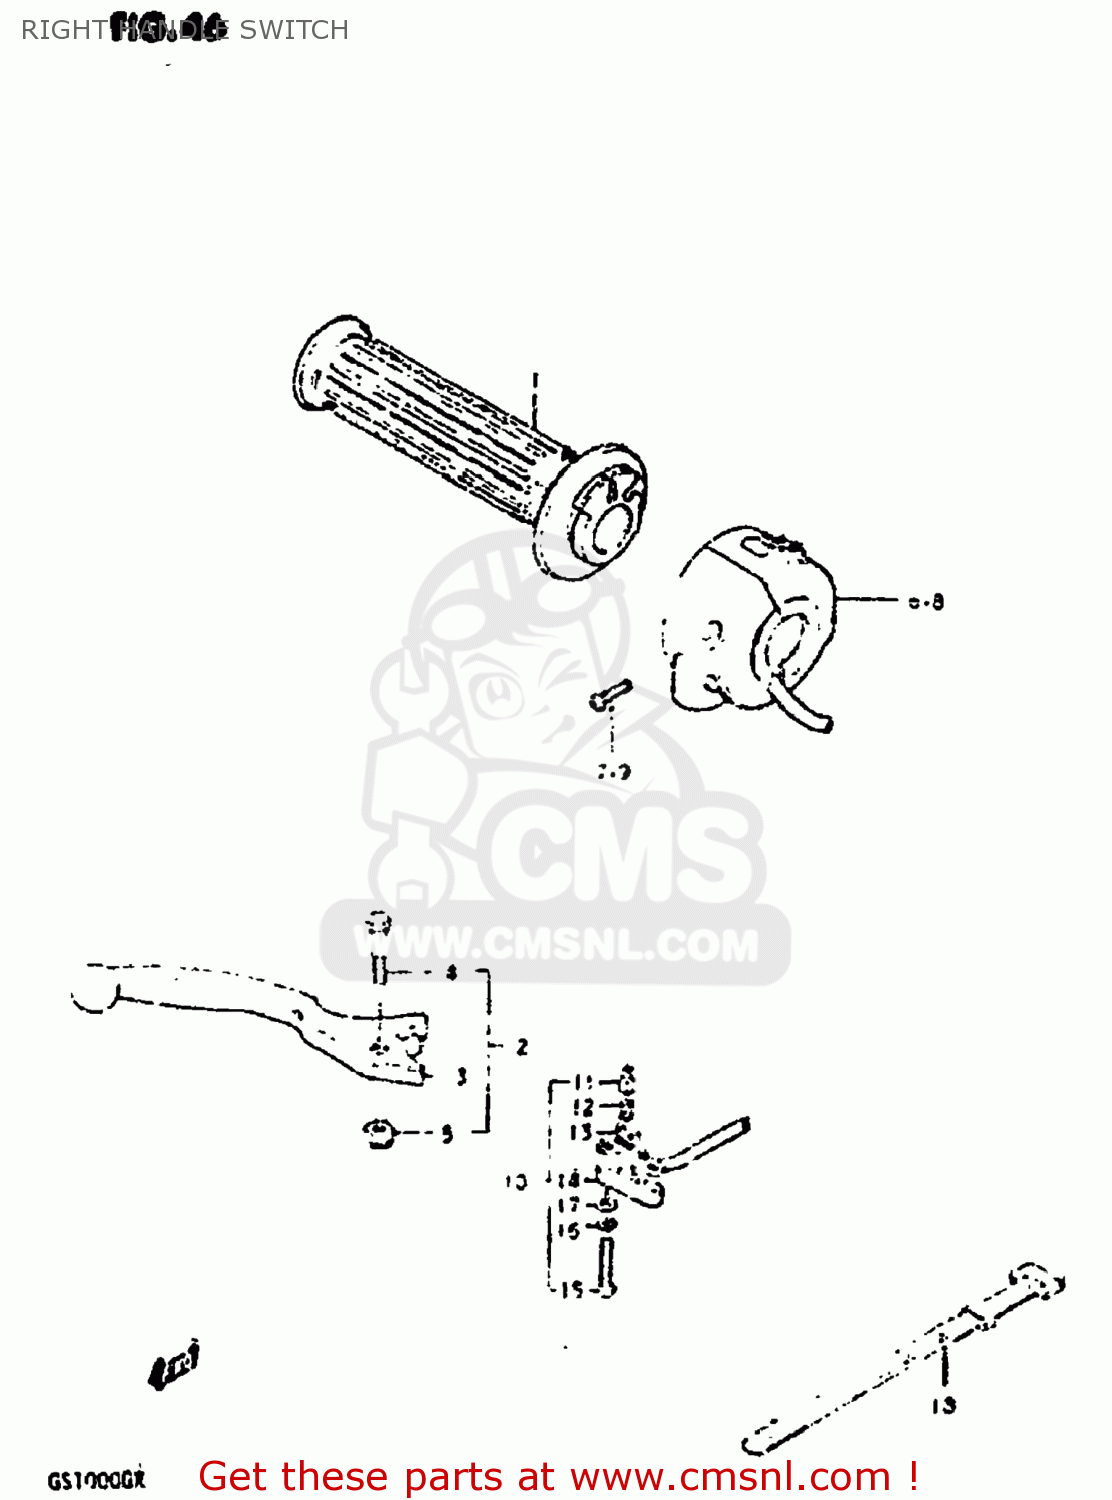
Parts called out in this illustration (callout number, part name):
1	GRIP,THROTTLE
2	LEVER ASSEMBLY,BRAKE
3	LEVER,BRAKE
4	BOLT
5	NUT 6MM
6	SWITCH ASSEMBLY,HANDLE,RIGHT
7	SCREW
8	SWITCH ASSEMBLY,HANDLE,RIGHT
9	SCREW
10	SWITCH ASSEMBLY
11	HOLDER
12	SPRING
13	PLATE
14	COVER,FR BK TERMINAL BASE
15	SCREW
16	LOCK WASHER
17	WASHER
18	CLAMP(L:120)
